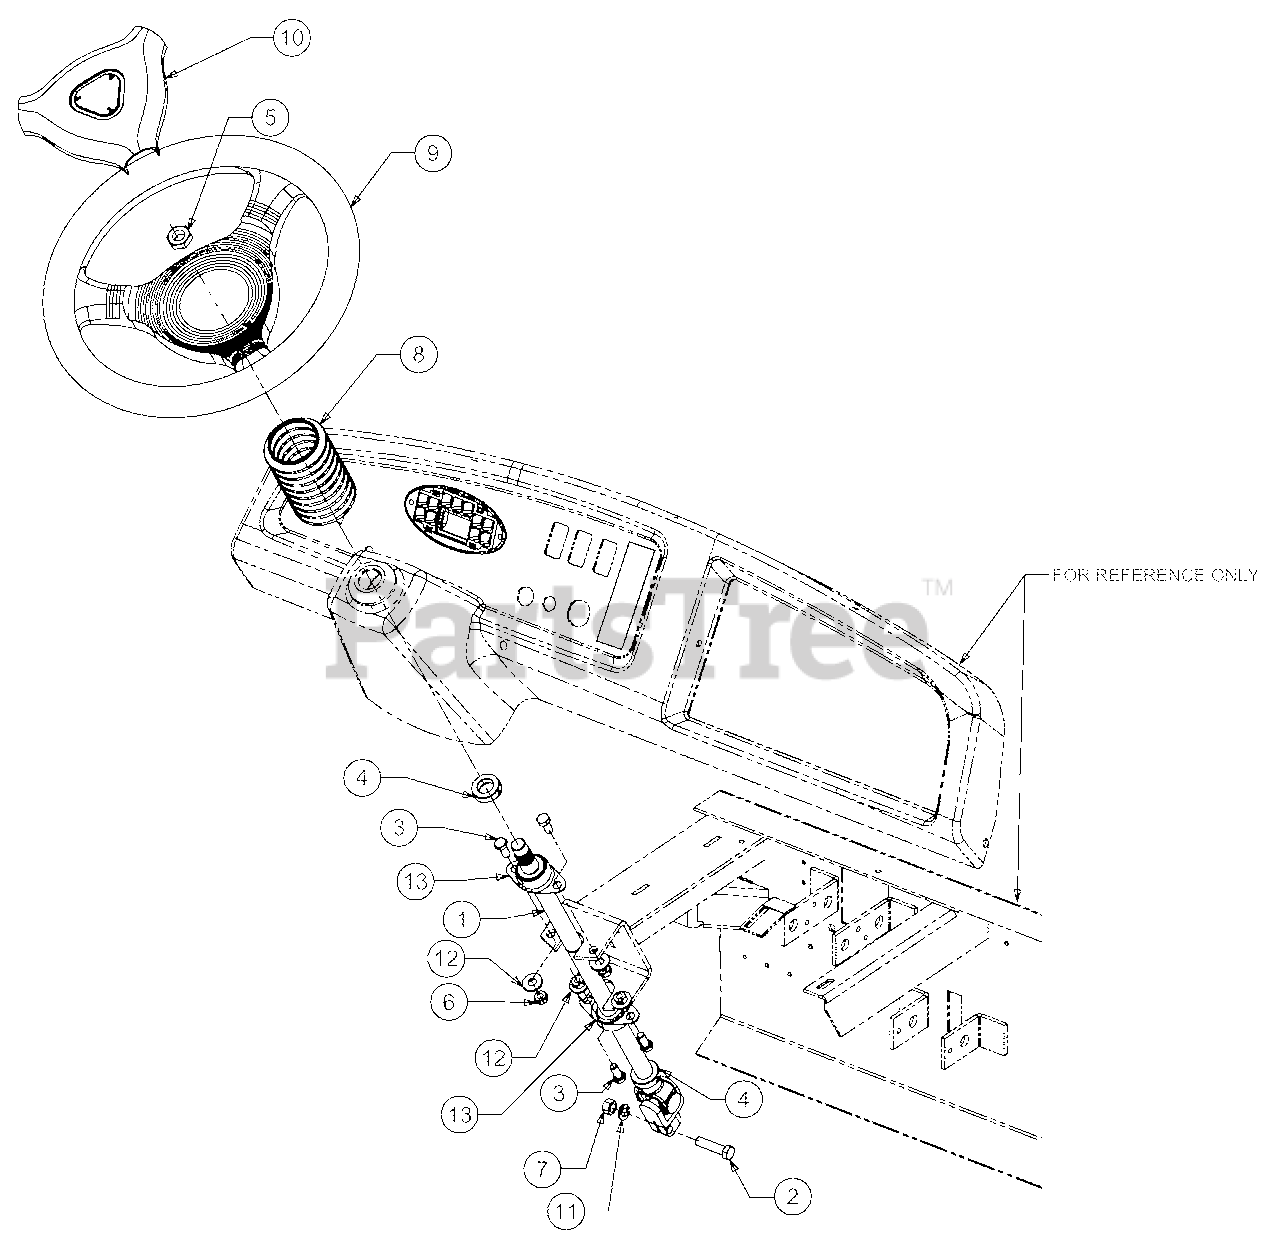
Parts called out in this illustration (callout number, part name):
1	Shaft Assembly, Steering
2	Hex Screw, 3/8-16, 1.50, Gr5
3	Hex Screw, 5/16-18, .75, Gr5
4	Collar, .75
5	Nut, Hex, M16-2, Class 8
6	Nut, Hex Lock, 5/16-18
7	Nut, Hex, 3/8-16, Gr8
8	Bellow, Steering, 4.75 Lg
9	Steering Wheel, Three-spoke
10	Cover, Steering Wheel
11	Washer, Lock, 3/8, Regular Duty
12	Washer, Flat, .385 ID x .870 OD x .092
13	Bearing, Flange, .75 ID, Self-Aligning
